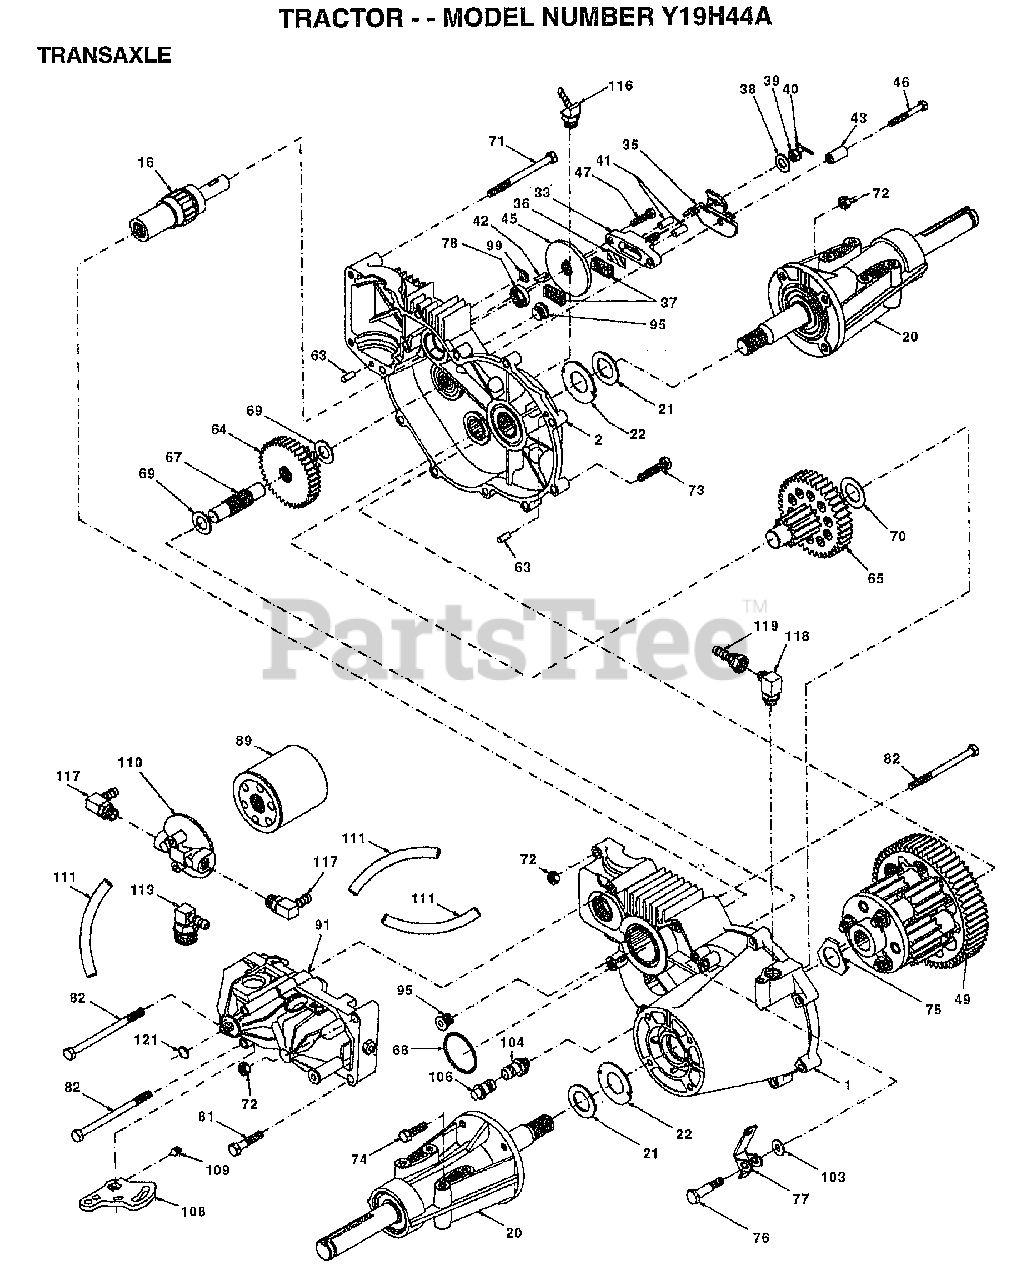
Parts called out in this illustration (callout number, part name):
1	HOUSING LH 70086
2	HOUSING RH 70088
16	SHAFT BRAKE 62877
20	AXLE MTG 70087
21	WASHER 44805
22	WASHER 44806
33	YOKE.BRAKE.62589
35	ARM BRAKE 50214
36	PUCK PLATE 44134
37	PUCK BRAKE 44132
38	WASHER HYD 44130
41	PIN BRAKE 44127
42	KEY HI PRO 44143
43	SPACER 50259
45	DISC BRAKE 44090
46	BOLT 1/4-20 44276
47	BOLT 1/4-20 44433
49	DIFFERENTIAL62834
63	PIN DOWL 44757
64	GEAR R14-38 44775
65	PINION DRIV 70051
67	SHAFT-44779
68	O RING 44781
69	WASHER 44795
70	WASHER 44794
71	BOLT 5/16 44827
72	NUT HXLK 43064
73	BOLT 5/16 44841
74	SCREW 5/16 45089
75	WASHER DIF 44880
76	BOLT SHOULD 44785
77	ARM FREEWHL 44786
78	SEAL.OIL.44761
81	BOLT 5/16 43084
82	BOLT 5/16 44820
89	FILTER SPIN 50037
95	PLUG.9005110-5600
103	WASHER.50169
104	CAP.VENT.70109
106	O-RING.ASM.70110
108	ARM.CONTROL.45007
109	SCREW.SET.50018.
110	FILTER.HEAD.50207
111	HOSE.5/16.50208.
113	FITTING.SAE.50210
116	FITTING.SAE.50213
117	FITTING.SAE.50249
118	FITTING.MAL.50251
119	FITTING.FEM.50250
121	RING.RET.2003016.
